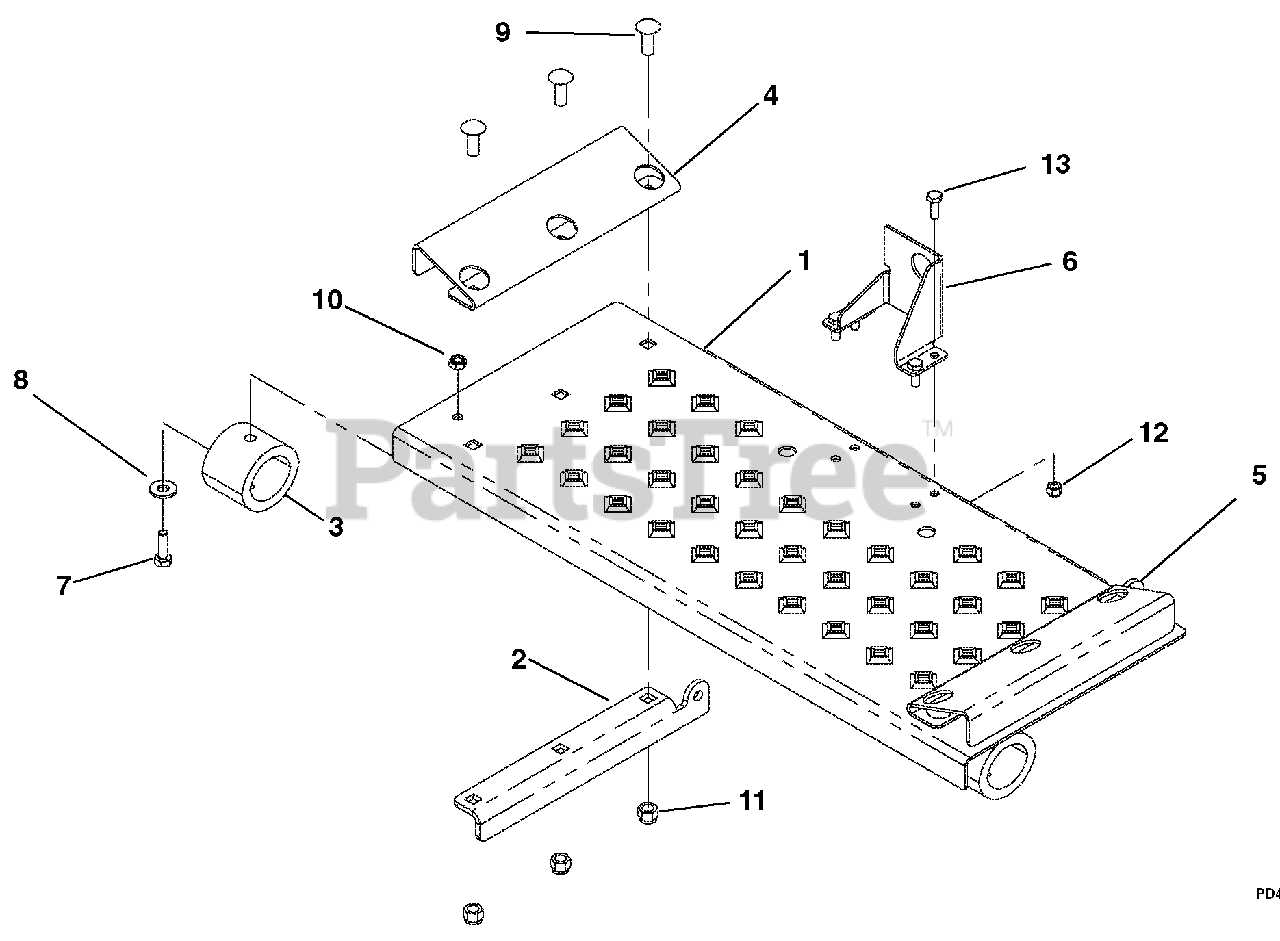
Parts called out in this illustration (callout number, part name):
1	Plate, Platform
2	Plate, Platform Tab RH
3	Bumper, Miner GBR-6
4	Wedge, Platform
5	Plate, Platform Tab LH
6	Anchor, OPC
7	Bolt, Hex .31-18 x 1.00 Grade 5
8	Washer, Flat, Steel .38 x .875 x .083
9	Bolt, Round Head Square Neck .38 x 1.00
10	Locknut, .312-18 Nyloc
11	Locknut, .38-16 Nyloc
12	Locknut, .25-20 Nyloc
13	Bolt, .25-20 x .750 Hex 5
